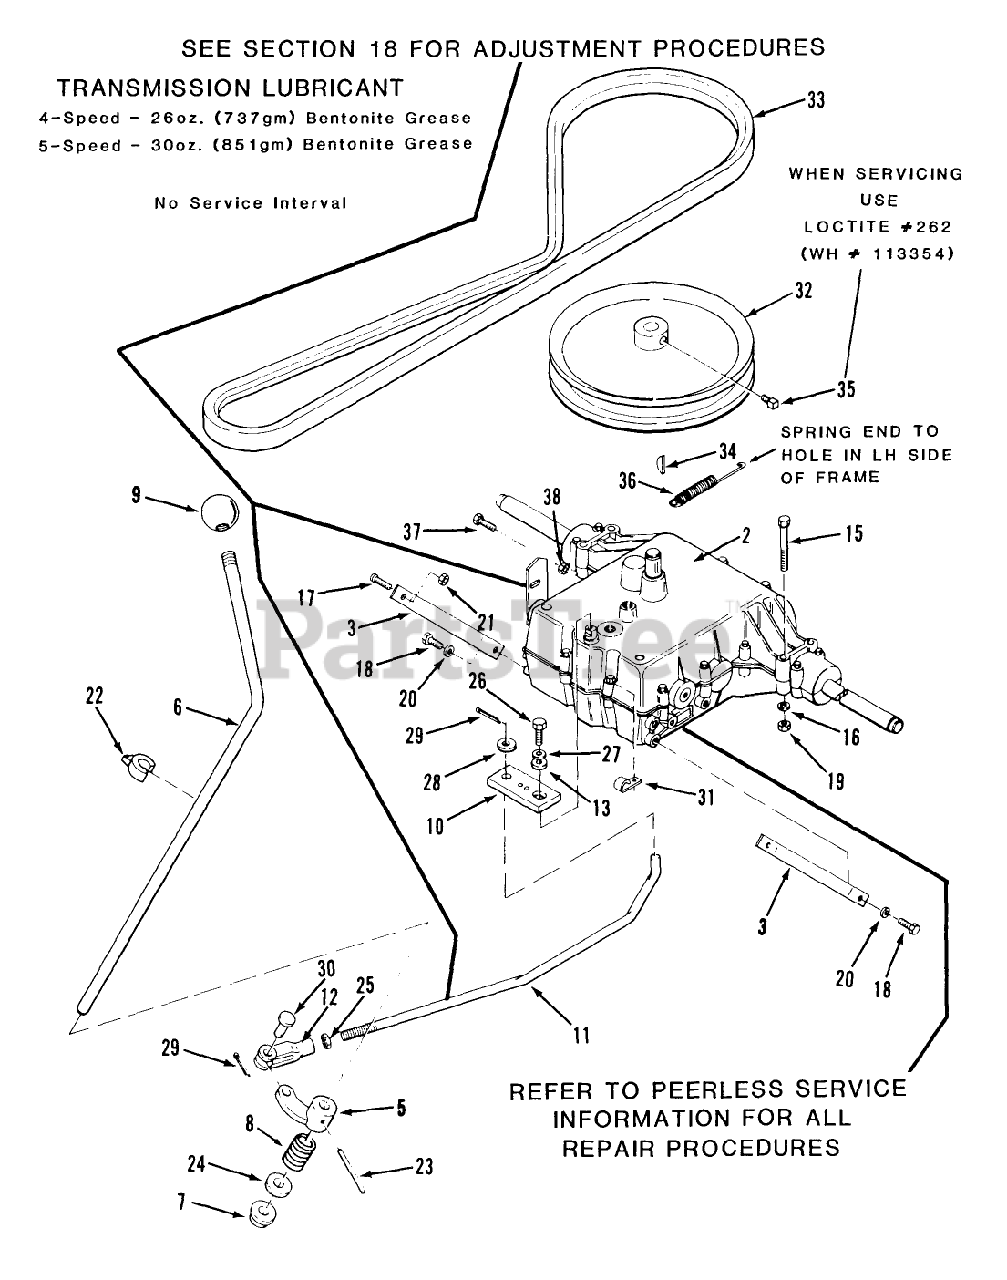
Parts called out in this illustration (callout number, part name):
2	Trans.-4-Spd.(Peerless Model 900-029) 210-4
3	TORQUE-STRAP R
5	ARM SHIFTER B
6	ROD SHIFT LEVER
7	BUSHING-NYLINER
8	SPRING COMPRESSION
10	ARM-TRANSMISSION R
11	ROD LINKAGE 3SPD
12	CLEVIS
13	WASHER
15	HHCS
16	WASHER 5/16 SAE
17	CARRIAGE BOLT -4
18	Screw
19	Nut
20	Lockwasher
21	Nut
22	POINTER
23	SPIROL PIN 7/32X21/2
24	SHIM-WASHER
25	Nut
26	Bolt 1/4-28 X 7/8
27	Washer
29	WASHER-SPECIAL
29	Cotter Pin
31	J-CLIP
32	Transmission Pulley
33	BELT-V
34	KEY-HI-PRO
35	Set Screw
36	SPRING-EXTENSION
37	Bolt
38	Nut
